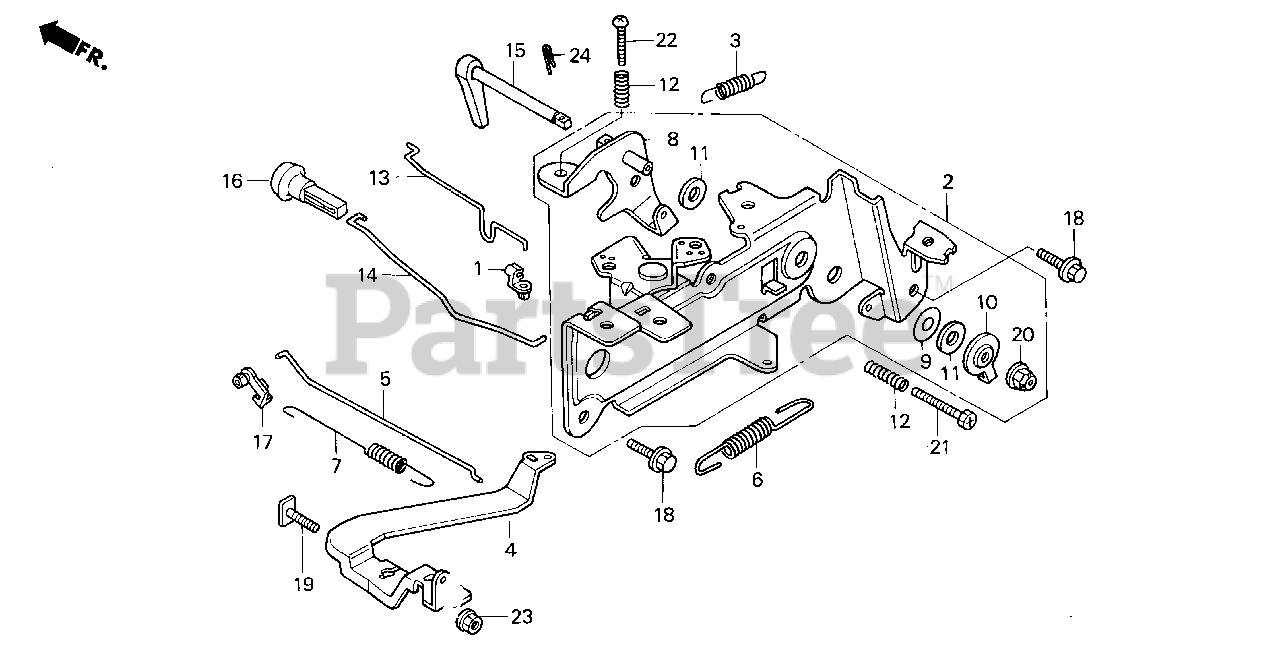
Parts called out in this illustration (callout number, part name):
1	JOINT, ROD
2	CONTROL ASSY.
3	SPRING, STARTER
4	ARM, GOVERNOR
5	ROD, GOVERNOR
6	SPRING, GOVERNOR (MANUAL)
7	SPRING, THROTTLE RETURN
8	ARM COMP., CONTROL
9	SPRING, LEVER
10	WASHER, CONTROL ARM
11	SPACER, CONTROL LEVER
12	SPRING, CONTROL ADJUSTING
13	ROD, CHOKE CONTROL
14	ROD, CHOKE KNOB
15	LEVER ASSY., THROTTLE
16	KNOB, CHOKE
17	BUSH, LINKAGE
18	BOLT, FLANGE (6X12) (CT200)
19	BOLT, GOVERNOR ARM
20	NUT, SELF-LOCK (6MM)
21	BOLT, SLOT (5X25)
22	SCREW, PAN (5X25)
23	NUT, FLANGE (6MM)
24	PIN, LOCK (10MM)
